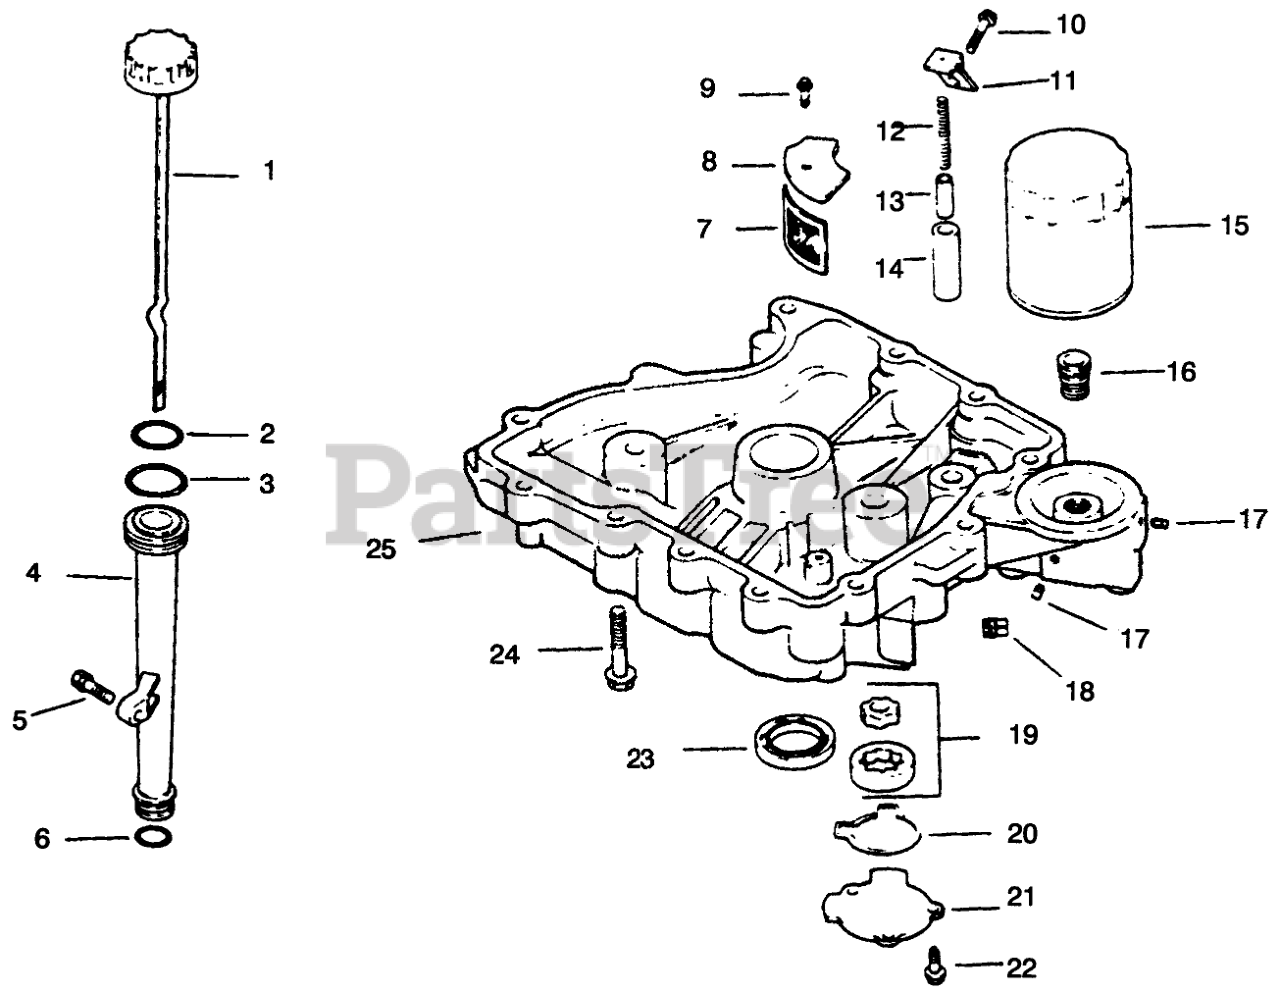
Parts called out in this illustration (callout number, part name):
1	Dipstick Assembly
2	Plug-Cup
2	"O"Ring-Dipstick
3	"O"Ring-Upper Tube
4	Tube-Oil Fill
5	Screw
6	"O"Ring-Lower Tube
7	Screen-Oil Pick Up
8	Cover-Oil Screen
9	Screw
10	Screw
11	Bracket-Oil Pump Relief Valve
12	Spring-Oil Pump Relief Valve
13	Piston-Oil Pump Relief Valve
14	Body-Oil Pump Relief Valve
15	Filter-Oil
16	Adapter-Oil Filter
17	Plug-SH 1/8
18	Plug
19	Pump-Oil Assembly
20	"O"Ring-Pump Cover
21	Cover-Oil Pump
22	Screw
23	Seal-Crankshaft
25	Pan-Oil
